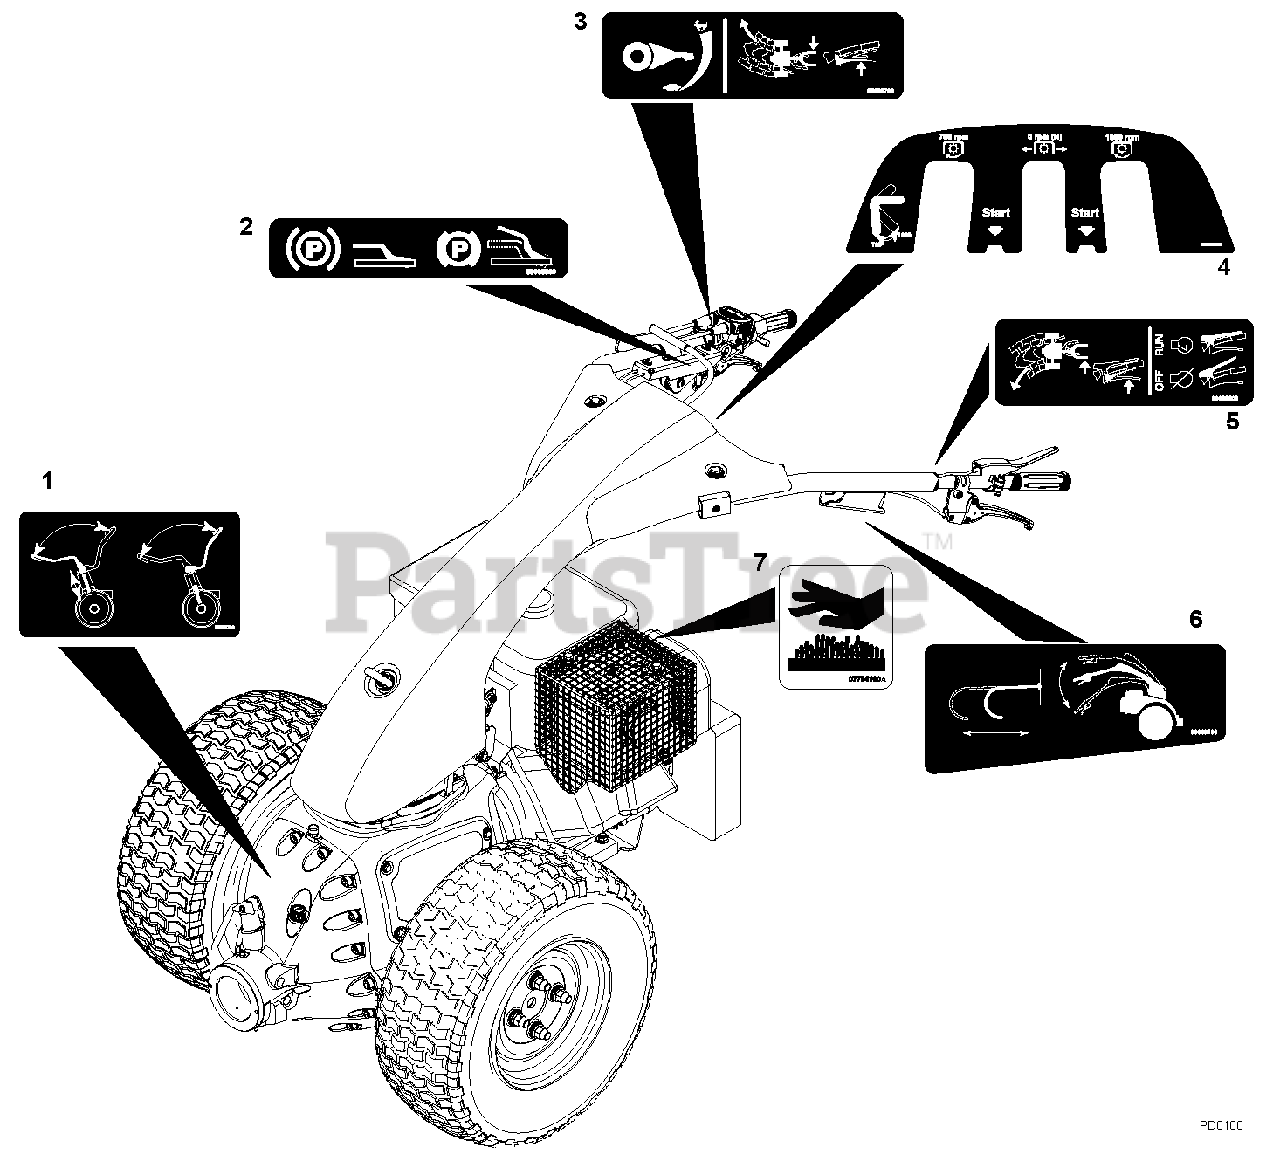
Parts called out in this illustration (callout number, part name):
1	Decal, Attachment Lock
2	Decal, Rapid U Park Brake
3	Decal, Rapid U Right Hand Lever Controls
4	Decal, Lever Controls "U"
5	Decal, Rapid U Left Hand Lever Controls
6	Decal, Handlebar Controls "U"
7	Decal, Hot Surface
